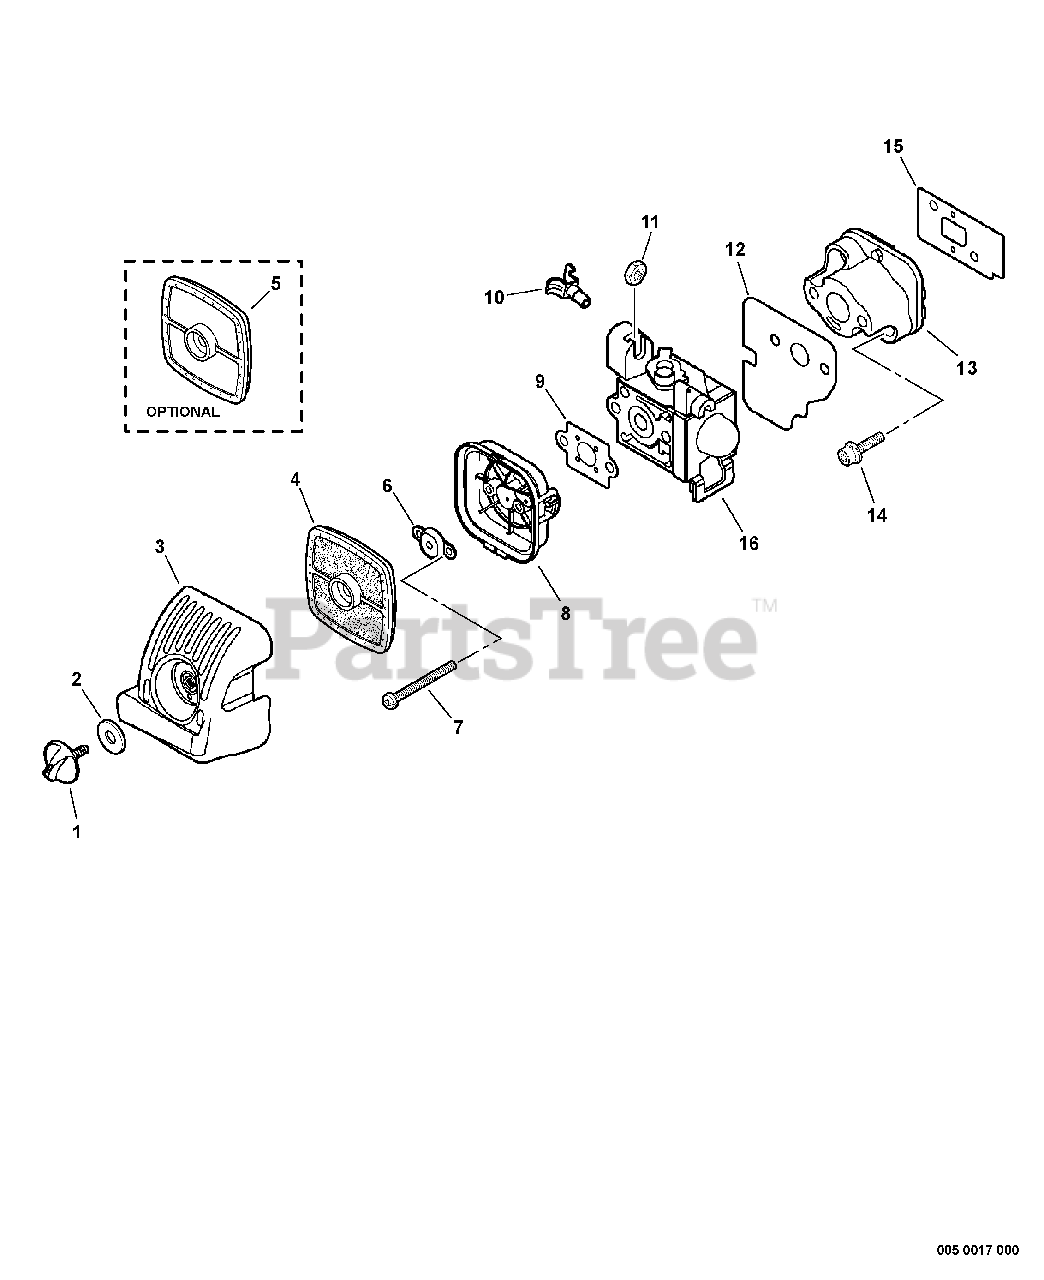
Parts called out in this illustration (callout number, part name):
1	THUMBSCREW
2	WASHER 5.5×16×0.8
3	COVER, AIR FILTER
4	FILTER, AIR - DOUBLE LAYER
5	FILTER, AIR - SINGLE LAYER
6	PLATE, PREVENT
7	BOLT 5×60
8	CASE ASSY, AIR FILTER
9	GASKET, INTAKE
10	GUIDE, CABLE
11	NUT - 6
12	GASKET, INTAKE
13	INSULATOR, INTAKE
14	BOLT 5×25
15	GASKET, INTAKE
16	CARBURETOR
